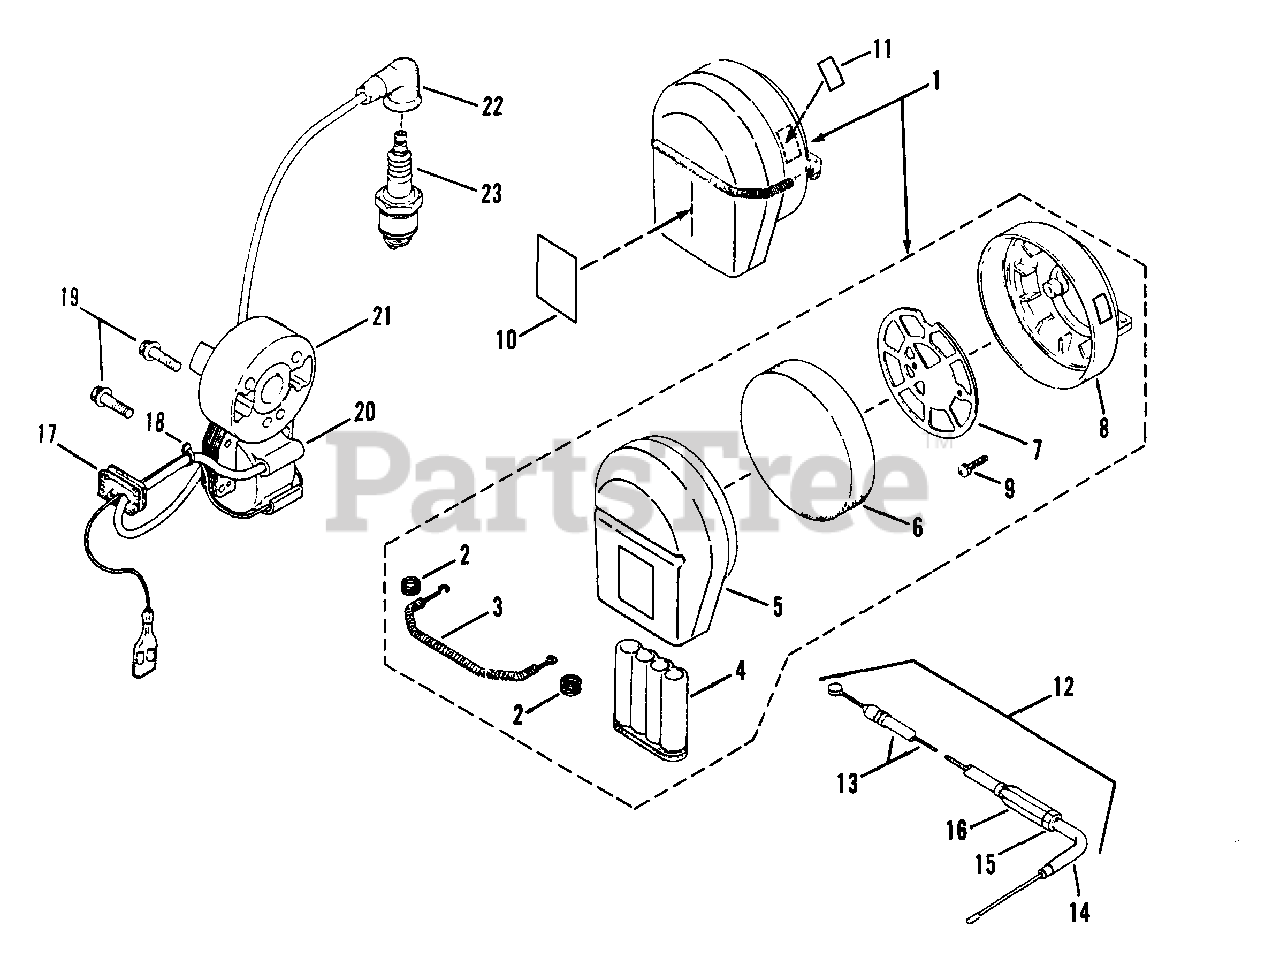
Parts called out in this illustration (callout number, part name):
1	AIR CLEANER ASSM'Y.
3	SPRING
4	CAP
5	COVER, Air Cleaner
6	ELEMENT, Air Cleaner
7	GRID
8	CASE, Air Cleaner
10	DECAL, Air Cleaner
11	DECAL, Choke
12	CABLE, Throttle Assembly
13	CABLE & JACKET
15	NUT, Lock
16	NUT, Adjusting
17	GROMMET
20	COIL, Ignition
22	BOOT, Spark Plug
